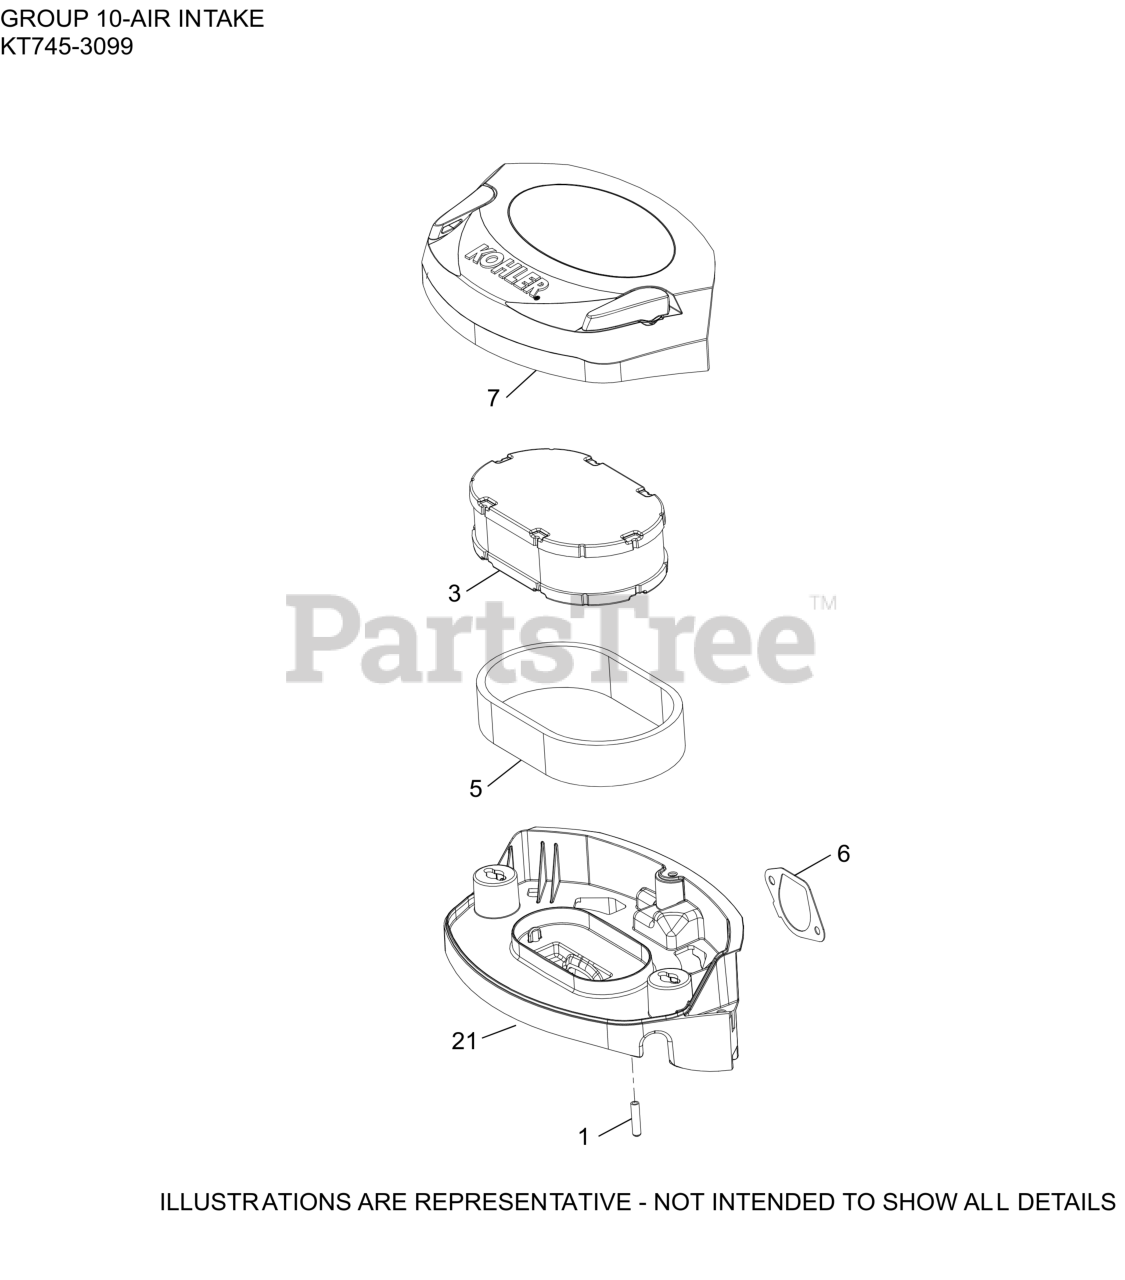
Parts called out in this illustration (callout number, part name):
1	CAP, MASKING
3	ELEMENT, AIR FILTER
5	ELEMENT, PRE-CLEANER
6	GASKET, AIR CLEANER BASE
7	COVER ASSEMBLY, AIR CLEANER
21	BASE ASSEMBLY, AIR CLEANER
